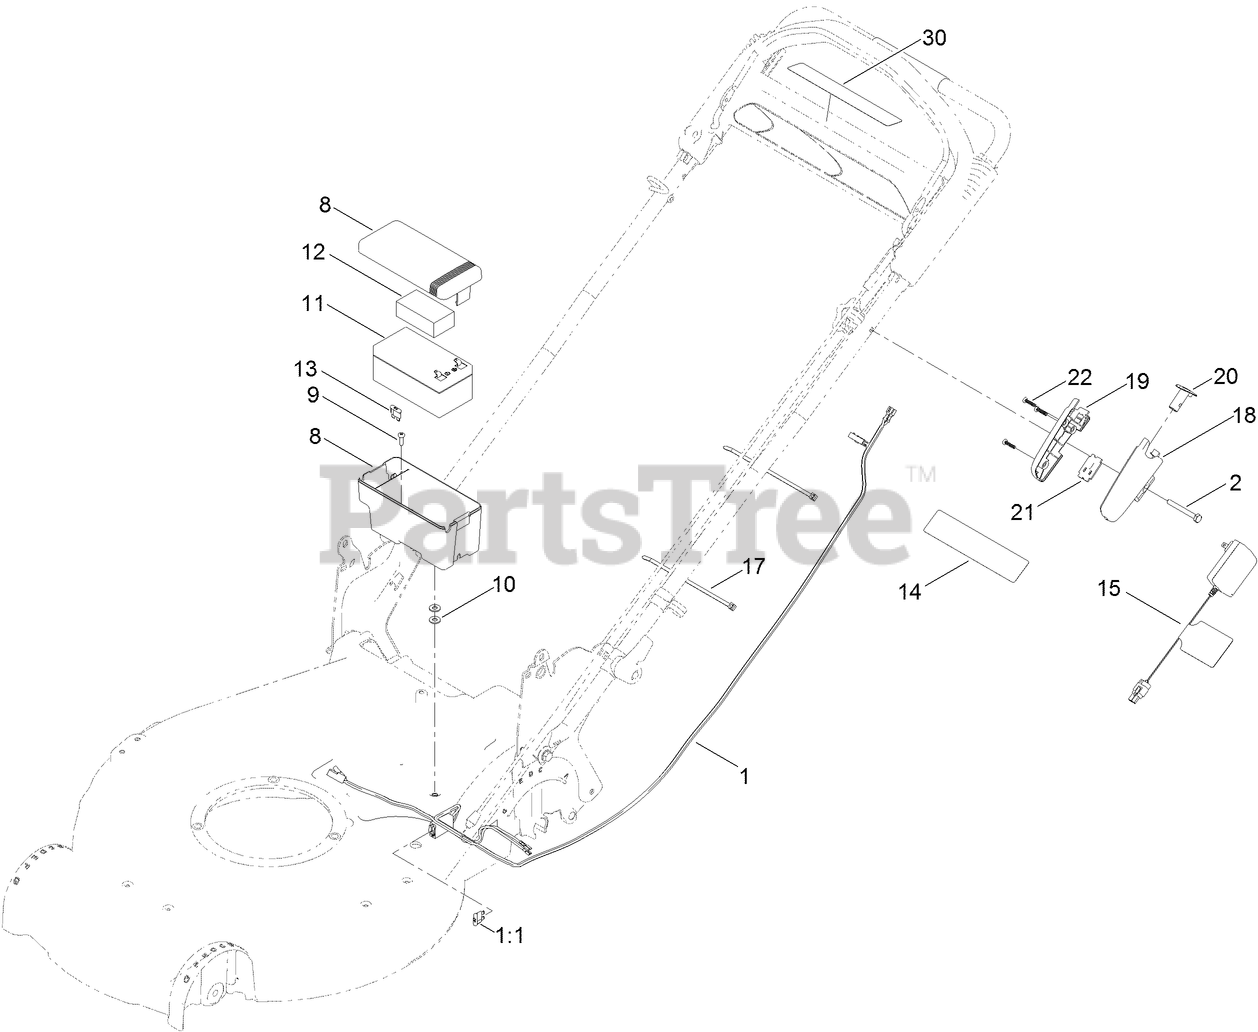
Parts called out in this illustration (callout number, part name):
1	HARNESS-WIRE
1:1	FUSE-40 AMP
2	SCREW-HH
8	BATTERY BOX ASM
10	WASHER-FLAT
11	BATTERY-WET
12	FOAM-BATTERY, TOP
13	FUSE-40 AMP
14	DECAL-WARNING
15	CHARGER, BATTERY (12V)
17	TIE-CABLE
18	HOUSING-SWITCH, LH
19	HOUSING-SWITCH, RH
20	BUTTON-SWITCH
21	SWITCH-PUSH BUTTON
22	SCREW-PPH
30	DECAL-BUTTON, PUSH
